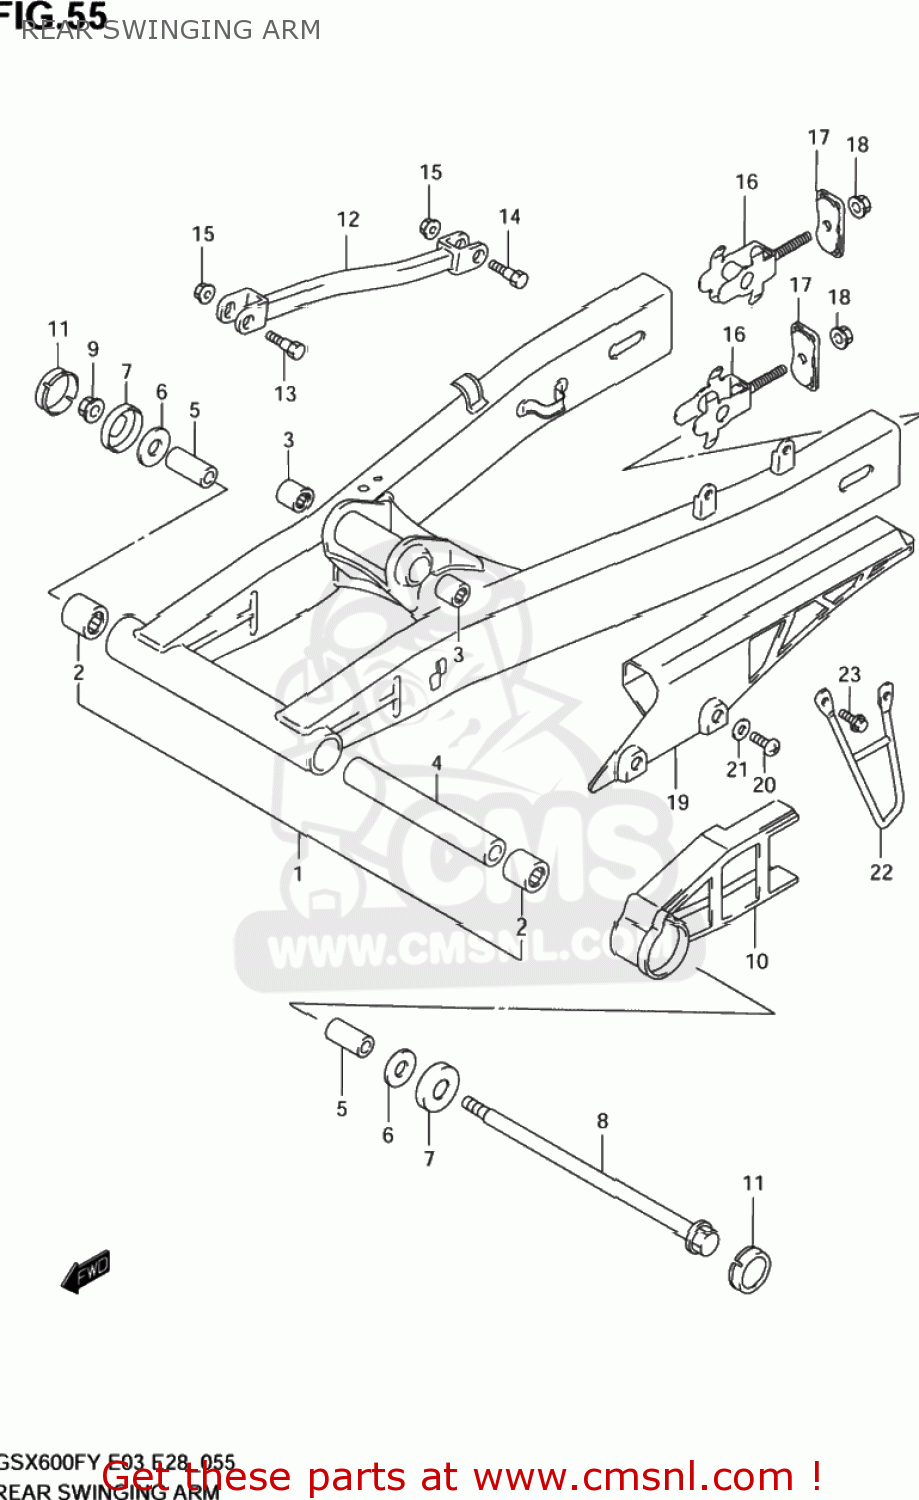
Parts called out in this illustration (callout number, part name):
1	SWINGINGARM ASSY,RR
2	BEARING(22X29X30)
3	BEARING(20X27X23.5)
4	SPACER,RR SWGARM PIVOT CTR
5	SPACER,RR SWGARM PIVOT
6	WASHER
7	COVER,RR SWGARM DUST SEAL
8	SHAFT,RR SWINGINGARM PIVOT
9	NUT
10	BUFFER,CHAIN TOUCH DEFENSE
11	CAP,SWINGINGARM PIVOT
12	TORQUELINK,RR
13	BOLT(10X39)
14	BOLT(10X34)
15	NUT
16	ADJUSTER,CHAIN
17	PLATE,CHAIN ADJ GUIDE
18	NUT
19	CASE,CHAIN
20	SCREW 6X12
21	WASHER
22	GUARD,CHAIN
23	BOLT
